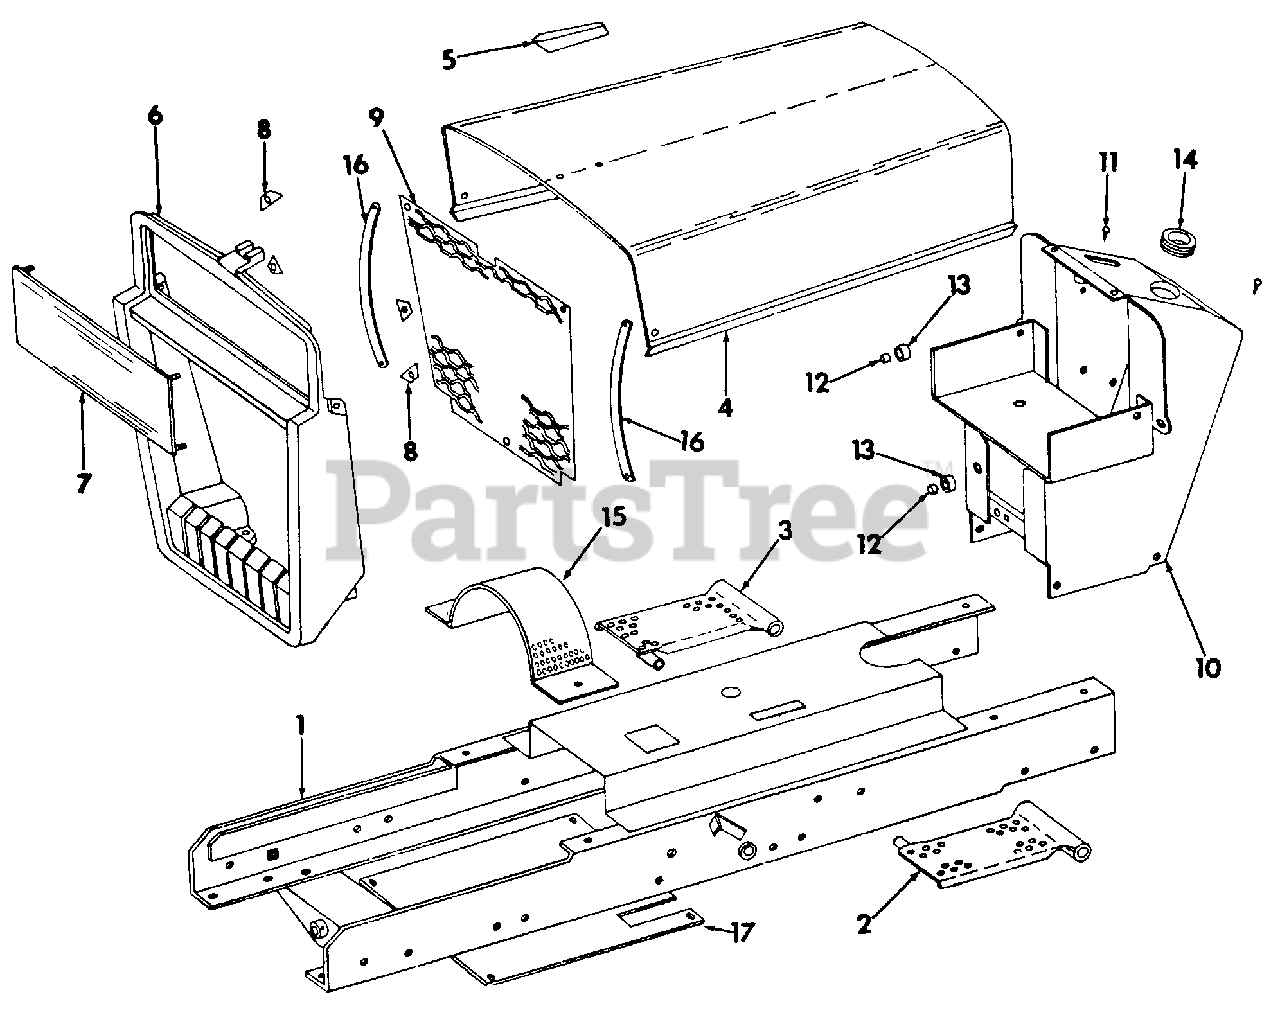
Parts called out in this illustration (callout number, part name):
1	Frame Assy
2	Support Assy, Foot LH
3	Support Assy, Foot RH
4	Hood Assy
5	Ornament, Hood
6	Grille
7	Strip Assy, Grille Panel
8	Strip, Grille Panel Clamp
9	Screen, Grille
10	Pedestal Assy
11	Bumper, Hood
12	Spacer, Hood Roller Lock
13	Roller, Hood Lock
14	Grommet, Instrument Panel
15	Shield, Clutch
16	Fastener, Grille Screen
17	Sheet, Bottom Clutch Shield
